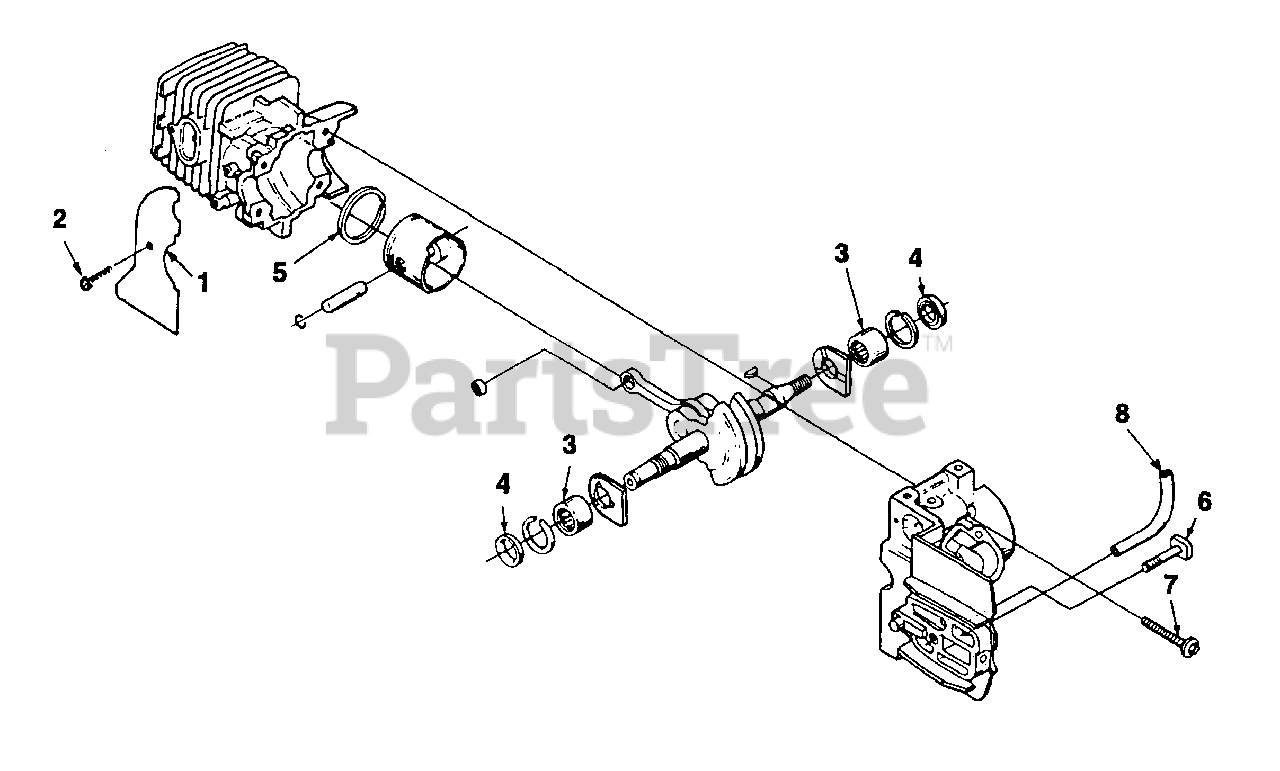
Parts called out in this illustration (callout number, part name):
1	SAW DUST SHIELD
2	SCREW-Tapping (#6-32 X 5/16")
3	BEARING-Needle
4	SEAL-Shaft
5	RING-Piston
6	BOLT-Guide Bar
7	SCREW-Pan Hd. (10-24 X 1 1/8")
8	TUBING-Rubber (4 1/4")
